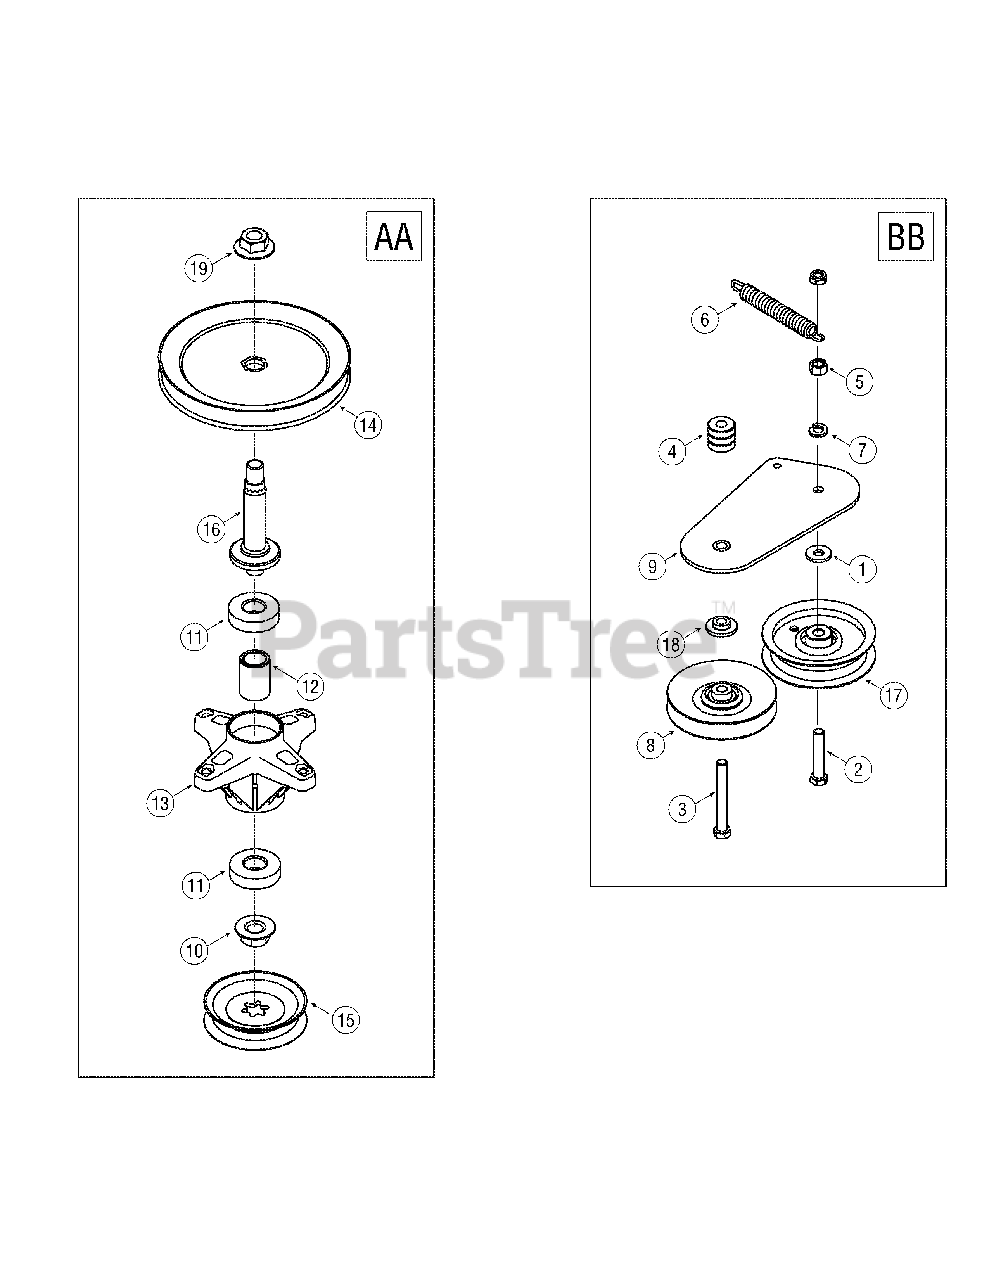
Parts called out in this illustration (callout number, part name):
1	Flat Washer, .38 x .93 x .11
2	Hex Cap Screw, 3/8-24 x 2
3	Hex Cap Screw, 3/8-16 x 3
4	Spacer
5	Hex Nut, 3/8-24
6	Extension Spring, .620 x 5.62
7	Lock Washer, 3/8
8	Idler pulley, 4" Diameter
10	HEX FLANGE NUT
11	Ball Bearing
12	Spacer
13	Deck Spindle Housing
14	Deck Pulley 7"
15	Pulley 3.75"
16	Spindle Shaft
17	Idler Pulley 3.50 dia.
18	Shoulder Spacer, .625 x .169
19	HEX FLANGE NUT
